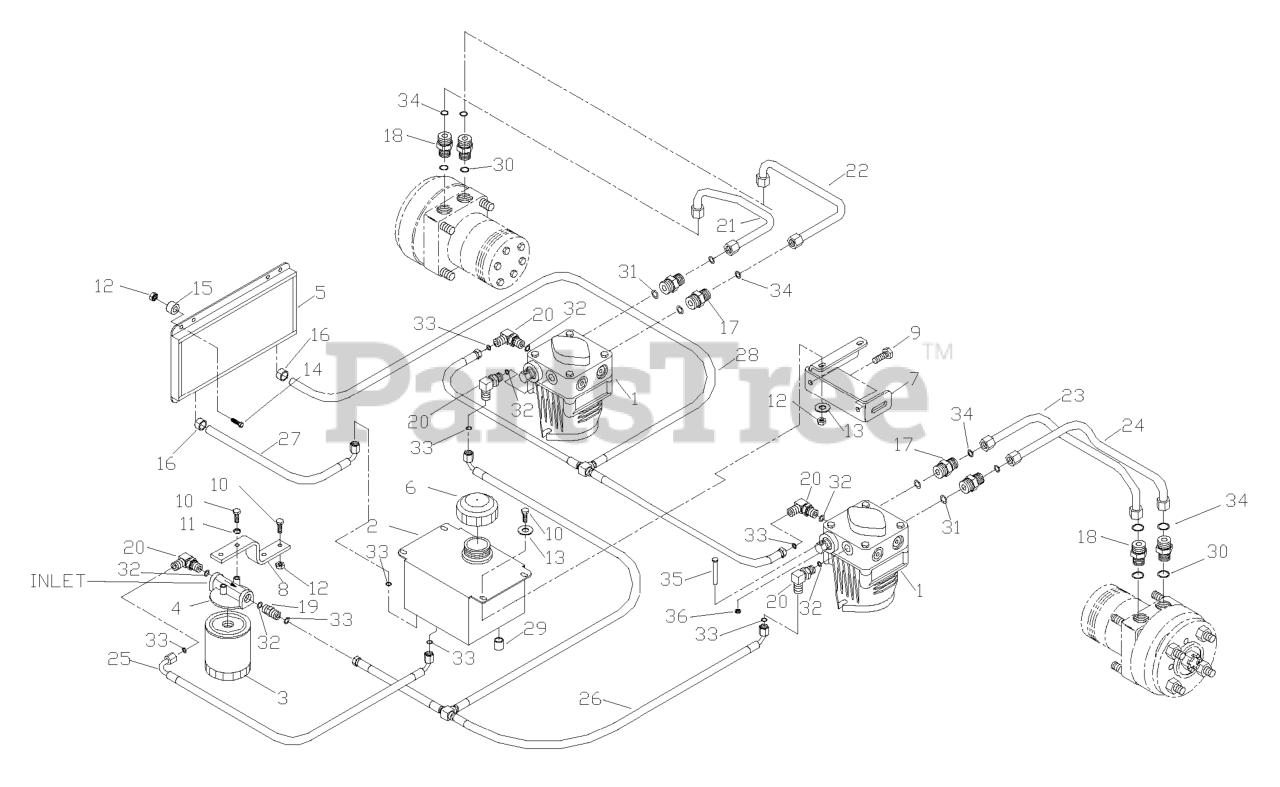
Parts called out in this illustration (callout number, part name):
1	PUMP
3	HYDRAULIC OIL FILTER
4	FILTER HEAD
6	HYDRAULIC CAP
7	TANK MOUNT LT
7	TANK MOUNT RT
8	FILTER MOUNT
9	HCS 5/16C X 3/4
10	HCS 1/4C X 3/4 HCS
11	LOCKWASHER 1/4"
12	NUT 1/4C CENTERLOCK
13	WASHER 1/4 FLAT
14	HCS 1/4-20.X
16	HOSE CLAMP T-1865
17	FITTING, STRAIGHT F6400-8-8-0
19	STRAIGHT FITG
20	ELBOW, F6801-6-6-0 90 DEGREE
21	RT. OUTSIDE TUBE
22	RT. INSIDE TUBE
23	LT.INSIDE TUBE
24	LT.OUTSIDE TUBE
29	NUT 9/16-18 JIC CAP
35	CLEVIS PIN
36	NUT PUSH
